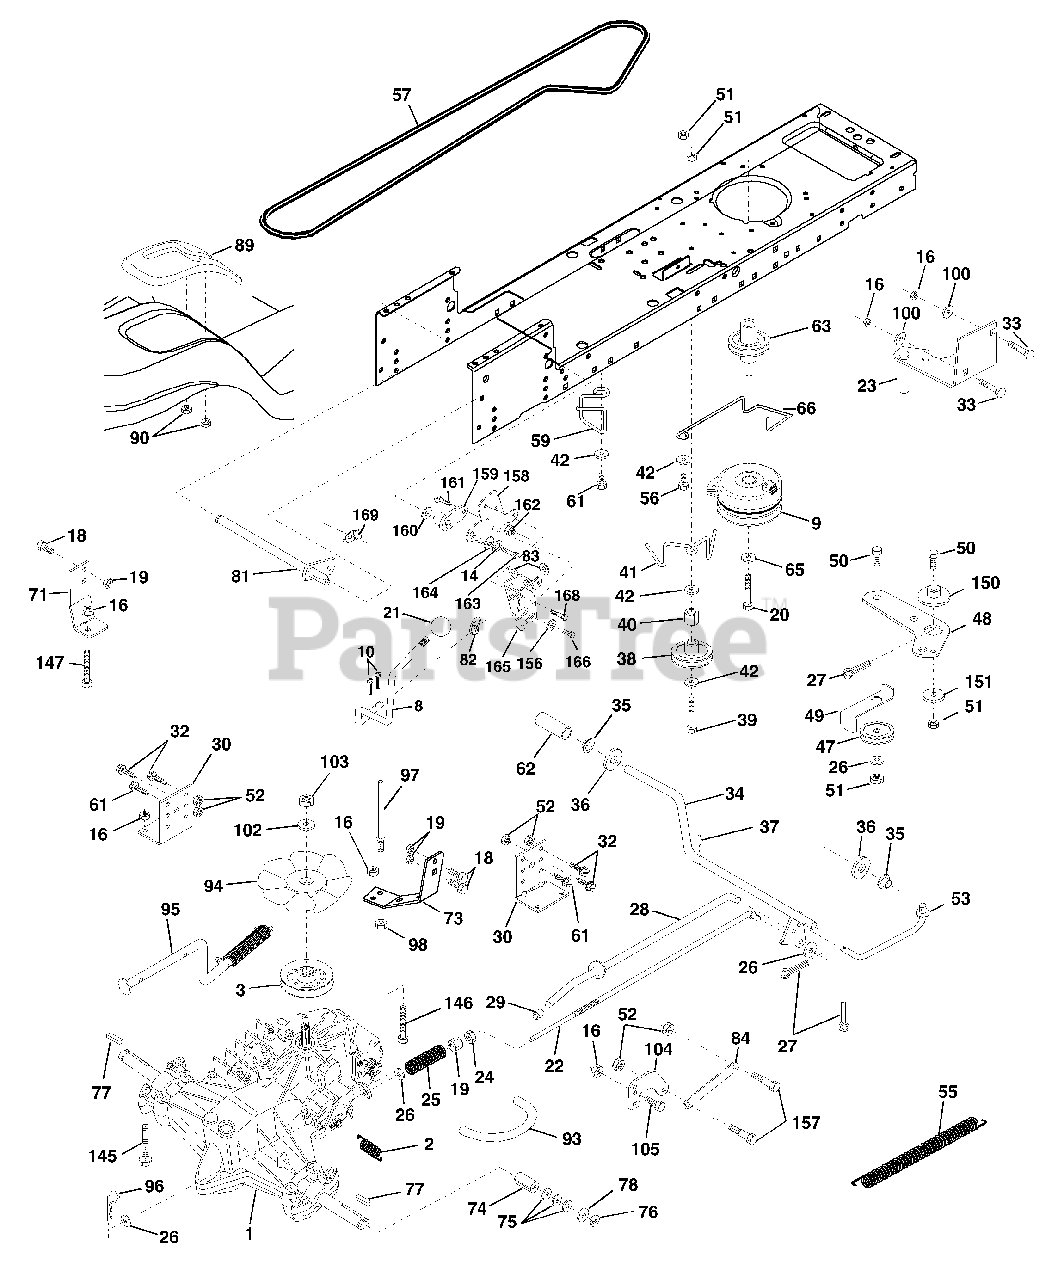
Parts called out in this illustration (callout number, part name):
2	Spring, Return, Brake
3	Pulley, Transaxle Hydro 750 LT
8	Rod Shift Fender Adjust STLT
9	Clutch Electric
10	Pin Cotter 1/8 x 1 CAD
14	Washer Lock Hvy Helical
16	Nut Lock Hex W/Ins. 5/16-18 Unc P
18	Bolt Fin Hex 3/8-16 Unc x 1 Gr.5
19	Nut Lock Hex W/Ins 3/8-16 Unc
20	Bolt, Hex 7/16-20 x 4-1/4 Ga. 5
21	Knob Deluxe 1/2-13 UNC BLK/BLK
22	Rod, Brake Hydro
23	Bracket Asm Mtg CL
24	Nut Hex Jam 3/8-16 UNC
25	Spring, Brake Rod
26	Washer
27	Pin Cotter 1/8 x 3/4 CAD.
28	Rod, Parking Brake
29	Cap,Parking Brake
30	Bracket, Transaxle
31	Keeper Belt Lh Lt 14 Ga
32	Bolt Hex Hd 5/16-18 Unc x 3/4
33	Bolt Carriage 5/16-18 UNC x 3/4
34	Shaft, Foot Pedal
35	Bearing, Nylon
37	Pin, Roll
38	Pulley, Idler, Flat
40	Spacer Split
41	Keeper, Belt Idler
42	Washer 13/32 x 13/16 x 12 Ga
47	Pulley, Idler, V-Groove Plastic
48	Bellcrank Clutch Grnd Drv STL
49	Retainer, Belt Style Spring
50	Bolt
52	Nut Crown Lock 5/16-18
53	Link, Clutch
55	Spring, Return, Clutch
56	Bolt, Fin Hex 3/8-16 UNC x 1 1/4
57	V-Belt, Ground Drive
59	Keeper, Center Span
61	Screw Thdrol. 3/8-16 x 3/4 Ty. TT
62	Cover, Pedal Premium
63	Pulley, Engine
65	Washer Lock Hvy HLCL Spr 7/16
66	Keeper Belt Engine
71	Strap Torque Lh Hydro 18/20" T
73	Strap Torque Rh Hydro 0650
74	Spacer, Split
75	Washer 25/32 x 1-1/4 x 16 Ga.
77	Key, Square
78	Washer 25/32 x 1-5/8 x 16 Ga
81	Shaft Asm Cross Tapered 650 20
82	Spring Torsion T/A
83	Washer 17/32 x 3/4 x 16 Ga.
84	Link Transaxle 0650 LT/YT/STL
89	Console, Shift Hydro STLT
90	Nut Self-Thd Wsh-Hd 1/4 Zinc
93	Line Fuel Hydro 4"
94	Fan, Hydro 7"
95	Control Asm. Bypass Hydro
96	Retainer Spring 1" Zinc/Cad
97	Keeper Belt Rh Hydro 0750.18/20"
98	Nut Keps Hex 3/8-16 Unc
100	Washer 11/32 x 3/4 x 16 Ga.
102	Washer Belleville .501D x 1.50D
103	Nut Hex Jam Toplock 1/4-20 Unf
104	Arm, Control Hydro
105	Screw Cap Hex 5/16 x 18 x 1
145	Bolt Hex 5/16-18 Unc Flghd
146	Bolt Hex Flghd 5/16-18 x 2-1/4
147	Bolt Hex Flghd 5/16-18 x 1-1/2
150	Bushing Bellcrank Grd Drive
151	Washer 13/32 x 2 x 10 Ga.
156	Washer Srrted 5/16ID x 1.125
157	Bolt Shoulder 5/16-18 Unc-2A
158	Bracket Shift Mount
159	Hub Tapered Flange Shift Lt
160	Washer 29/32 x 1-1/4 x 16 Ga
161	Bolt Rdhd Sqnk 1/4-20 x 3/4 Gr 5
162	Nut Crownlock 1/4-20 Unc
163	Bolt Hex Fin 1/4-20 Unc x 1 Gr 5
164	Washer 5/8 x .281 x 10 Ga
165	Bracket Pivot Lever
166	Screw 5/16-18 x 5/8
168	Bolt Shoulder 5/16-18 x .561
169	Plate Fastening STLT/CRD
